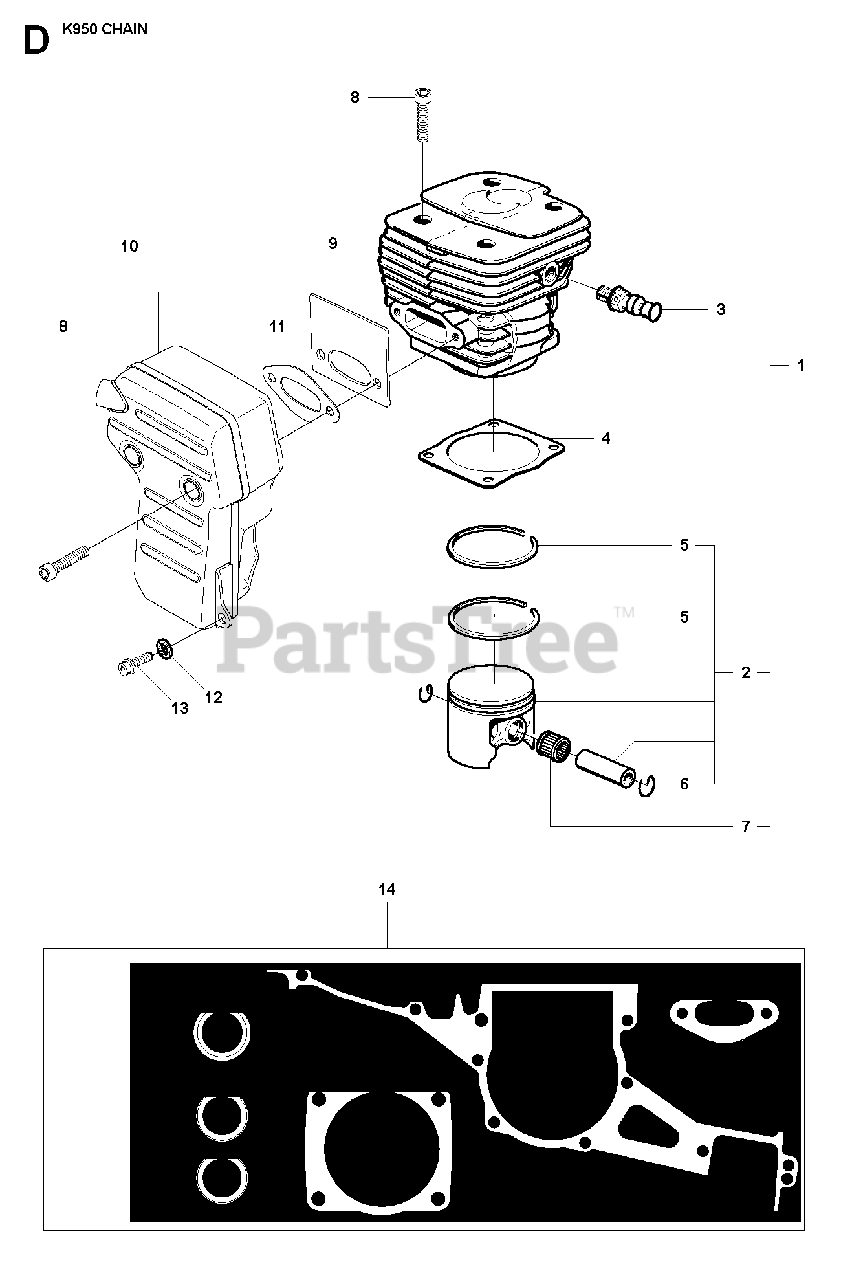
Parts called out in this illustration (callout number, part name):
1	CYLINDER ASSYIncl. 2, 7
2	PISTON ASSYIncl. 5, 6
3	DECOMPRESSION VALVE
4	CYLINDER BASE GASKETGasket kit 14
7	NEEDLE BEARING
9	COOLING PLATE
10	MUFFLER ASSYIncl. 8, 12
11	GASKETGasket kit 14
13	SCREW IHSCFM
16	SEALING RING
